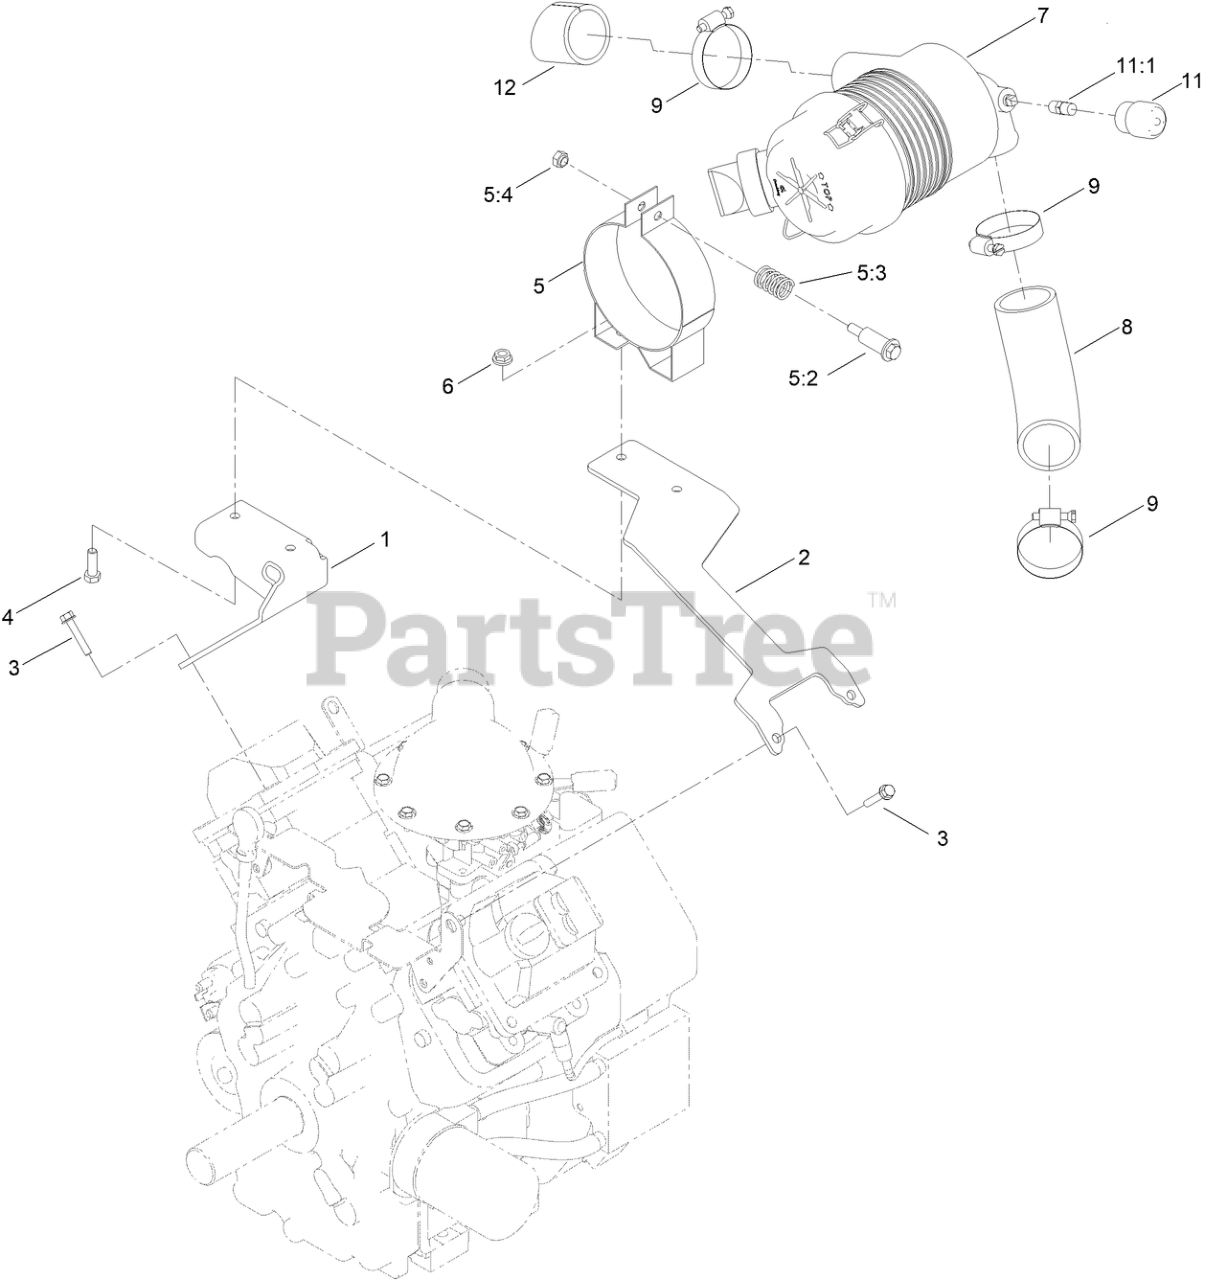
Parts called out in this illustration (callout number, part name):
1	BRACKET-SUPPORT, RIGHT
2	BRACKET-SUPPORT, LEFT
3	SCREW-HHF
4	SCREW-HH
5	AIR CLEANER MOUNTING BAND ASM
5:3	SPRING
5:4	NUT
6	NUT-HF
7	AIR CLEANER ASM
8	HOSE-AIR CLEANER
9	CLAMP-HOSE
11	INDICATOR
11:1	ADAPTER-INDICATOR
12	TUBE-INLET, AIR
